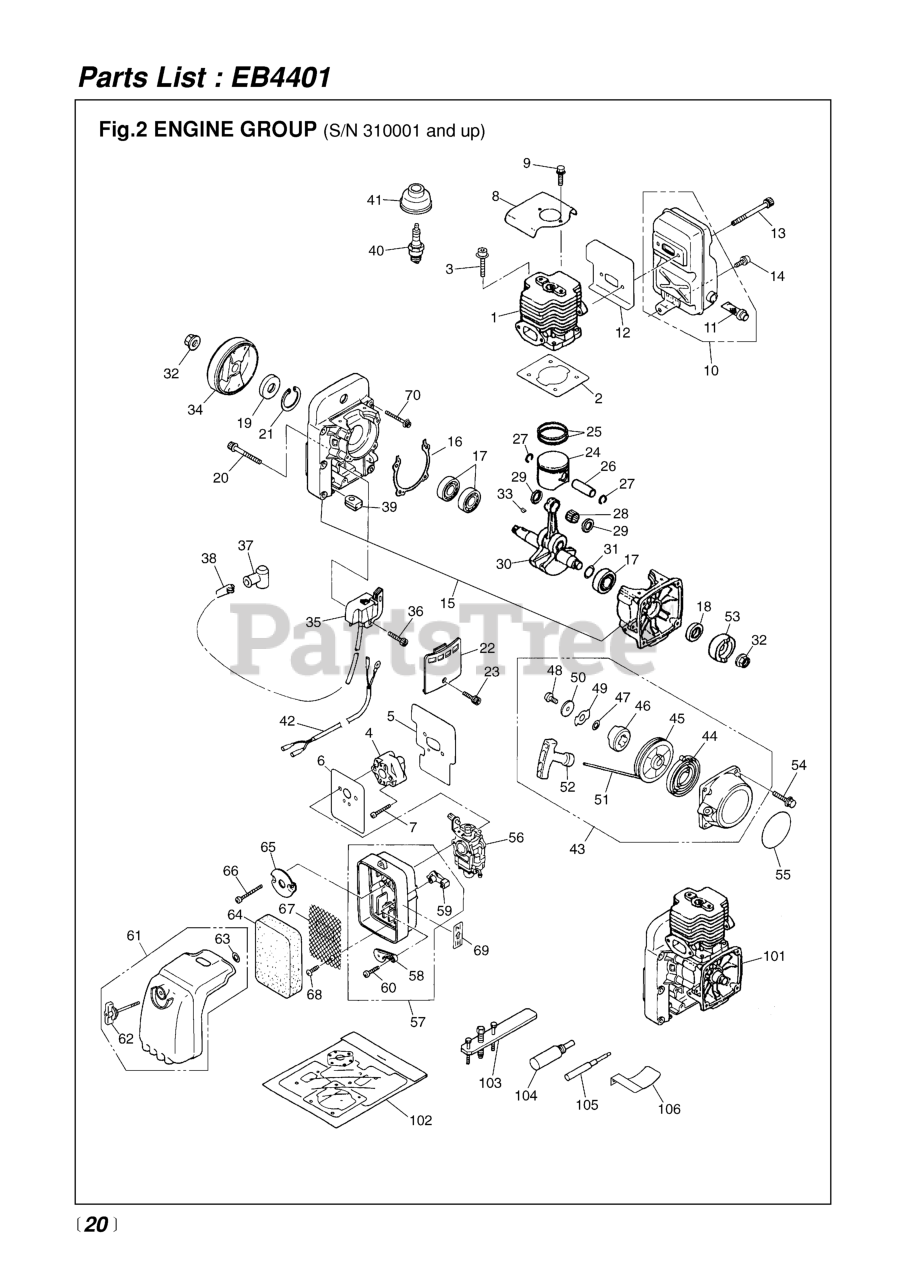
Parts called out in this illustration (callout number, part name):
1	CYLINDER(REPLACES-12113)
2	GASKET, BASE
3	BOLT, M5 X 22
4	INSULATOR (REPLACES-13160)
5	GASKET
6	GASKET
7	BOLT
9	BOLT, M5 x 10
11	ARRESTER
12	GASKET
13	BOLT, M6 X 70
14	BOLT, M6 X 12
15	CRANKCASE COMPL
16	GASKET
17	BEARING (REPLACES 2810-21240)
18	SEAL, OIL 15 X 25 X 7
19	SEAL (REPLACES 1400-21220)
20	BOLT, M5 X 30
21	RING, SNAP, M35 X 1.5
22	COVER
23	BOLT, M4 X 16
24	PISTON (RPLS -41110)
25	RING, PISTON (RPLS -41210)
26	PIN, PISTON (RPLS. 1490-41316)
27	RING, SNAP
28	BEARING
29	WASHER (RPLS 1491-41510)
30	CRANKSHAFT COMPLETE
31	SHIM (REPLACES 848-870-G000)
32	NUT, M10
33	KEY
34	ROTOR (REPLACES -71110)
35	COIL ASSEMBLY, IGINITION
36	BOLT, M4 x 20
37	CAP
38	SPRING
39	GROMMET
40	SPARK PLUG
41	CAP
42	CORD COMPLETE
43	RECOIL ASSY (RPLS -75100)
44	SPRING (RPLS -75220)
46	DOG
47	WASHER
48	SCREW
49	RETAINER (RPLS 1861-75161)
50	WASHER
51	ROPE
52	KNOB
53	PULLEY (RPLS -75210)
54	BOLT, M5 x 20
55	LABEL, RECOIL
56	CARBURETOR ASSEMBLY
57	BODY, CLEANER
58	PLATE
59	LEVER
60	SCREW
61	COVER, CLEANER (RPLS -82200)
62	KNOB
63	RING
64	ELEMENT (RPLS -82310)
65	PLATE (REPLACES -82511)
66	SCREW, M5 x 60
67	SCREEN (RPLS -82351)
68	SCREW
69	LABEL
70	BOLT, M6 X 40
101	SHORT BLOCK (RPLS -05010)
102	KIT, GASKET
103	PULLER ASSY
104	STOPPER (TOOL) (RPLS 3320-9641
105	GUIDE (TOOL)
